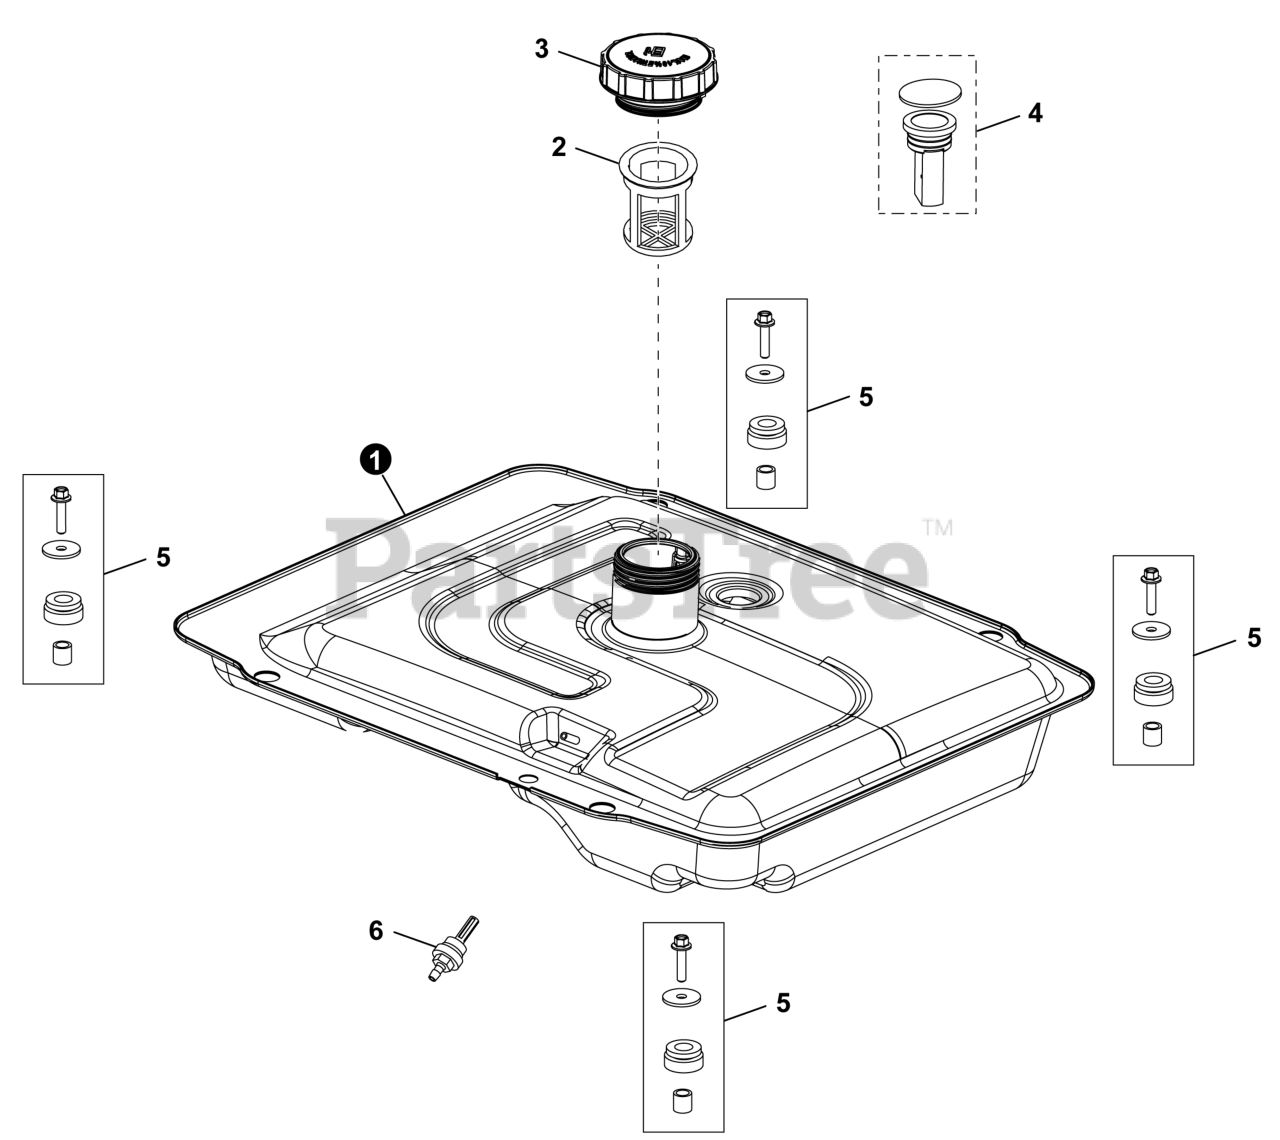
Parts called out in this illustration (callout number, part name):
1	ASSY., FUEL TANK
2	STRAINER?FUEL
3	CAP, FUEL
4	ASSY., FUEL LEVEL
5	KIT, TANK MOUNT
6	OUTLET, FUEL TANK
